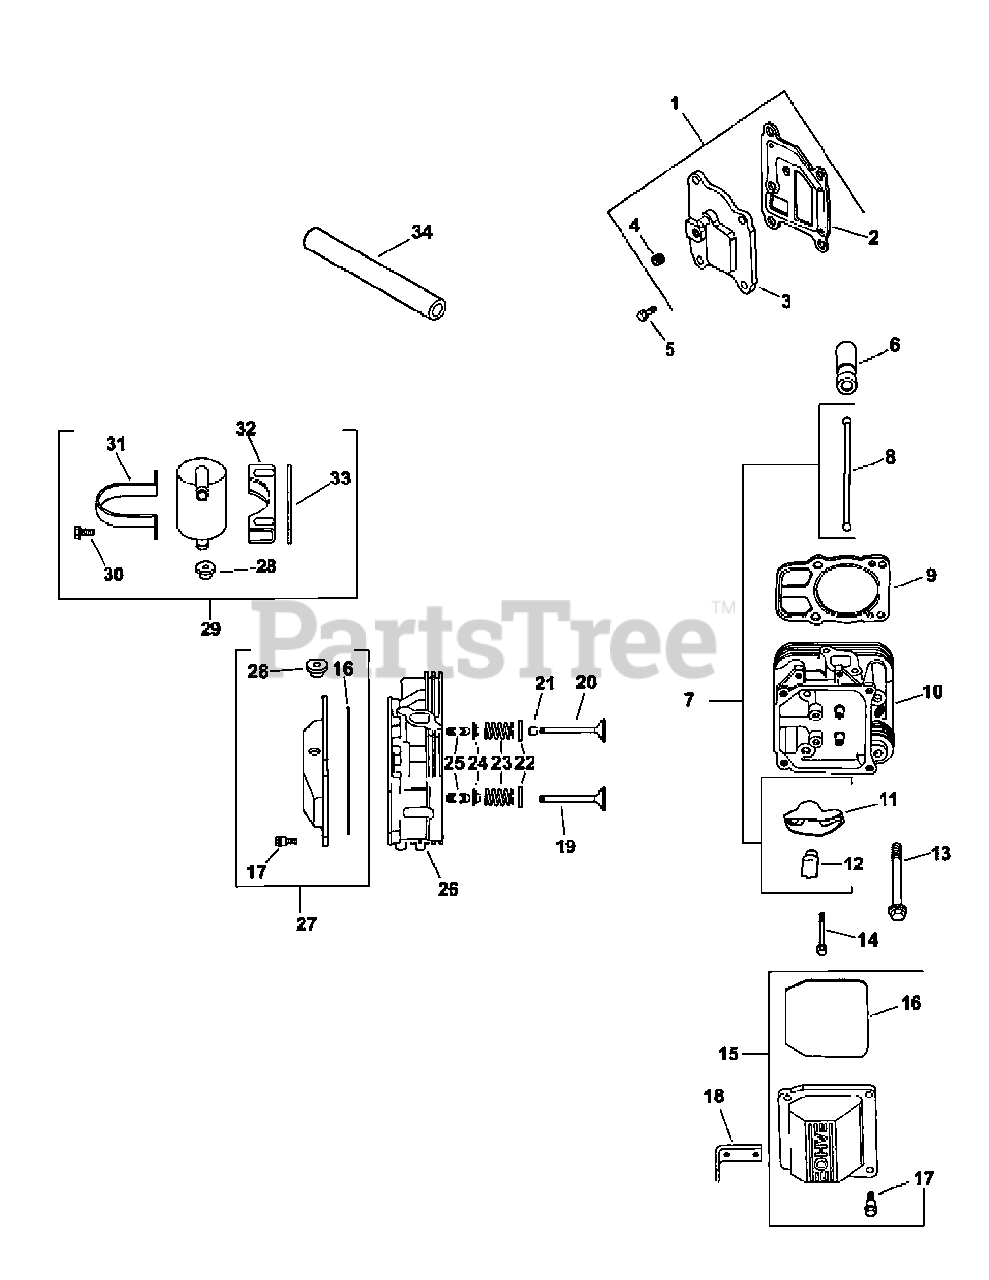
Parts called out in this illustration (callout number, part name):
1	Breather Cover w/Gasket Kit
2	Breather Gasket
3	Breather Cover
4	Plug, Pipe 1/8"
5	Hex Flange Screw (M6 x 1.0 x 20)
6	Valve Lifter
7	Valve Train Kit
9	Cylinder Head Gasket
10	Head Assembly # 2 Cylinder
12	Rocker Arm Pivot
13	Screw, Hex Flange
14	Hex Flange Screw (M6 x 1.0 x 34)
15	Valve Cover Kit
17	Screw, Shoulder (M6 x 1.0 x 30)
18	Lifting Strap
19	Exhaust Valve (Std.)
19	Exhaust Valve (.025)
20	Intake Valve (Std.)
20	Intake Valve (.025)
21	Valve Stem Seal
22	Spring Retainer
23	Valve Spring
24	Valve Spring Cap
25	Retainer Kit
26	Head Assembly # 1 Cylinder
27	Breather Valve Cover Kit
28	Rubber Grommet
29	Breather Seperator Kit
30	Hex Flange Screw (M5 x .8 x 16)
31	Breather Strap
32	Breather Seperator Bracket
34	Breather Hose
